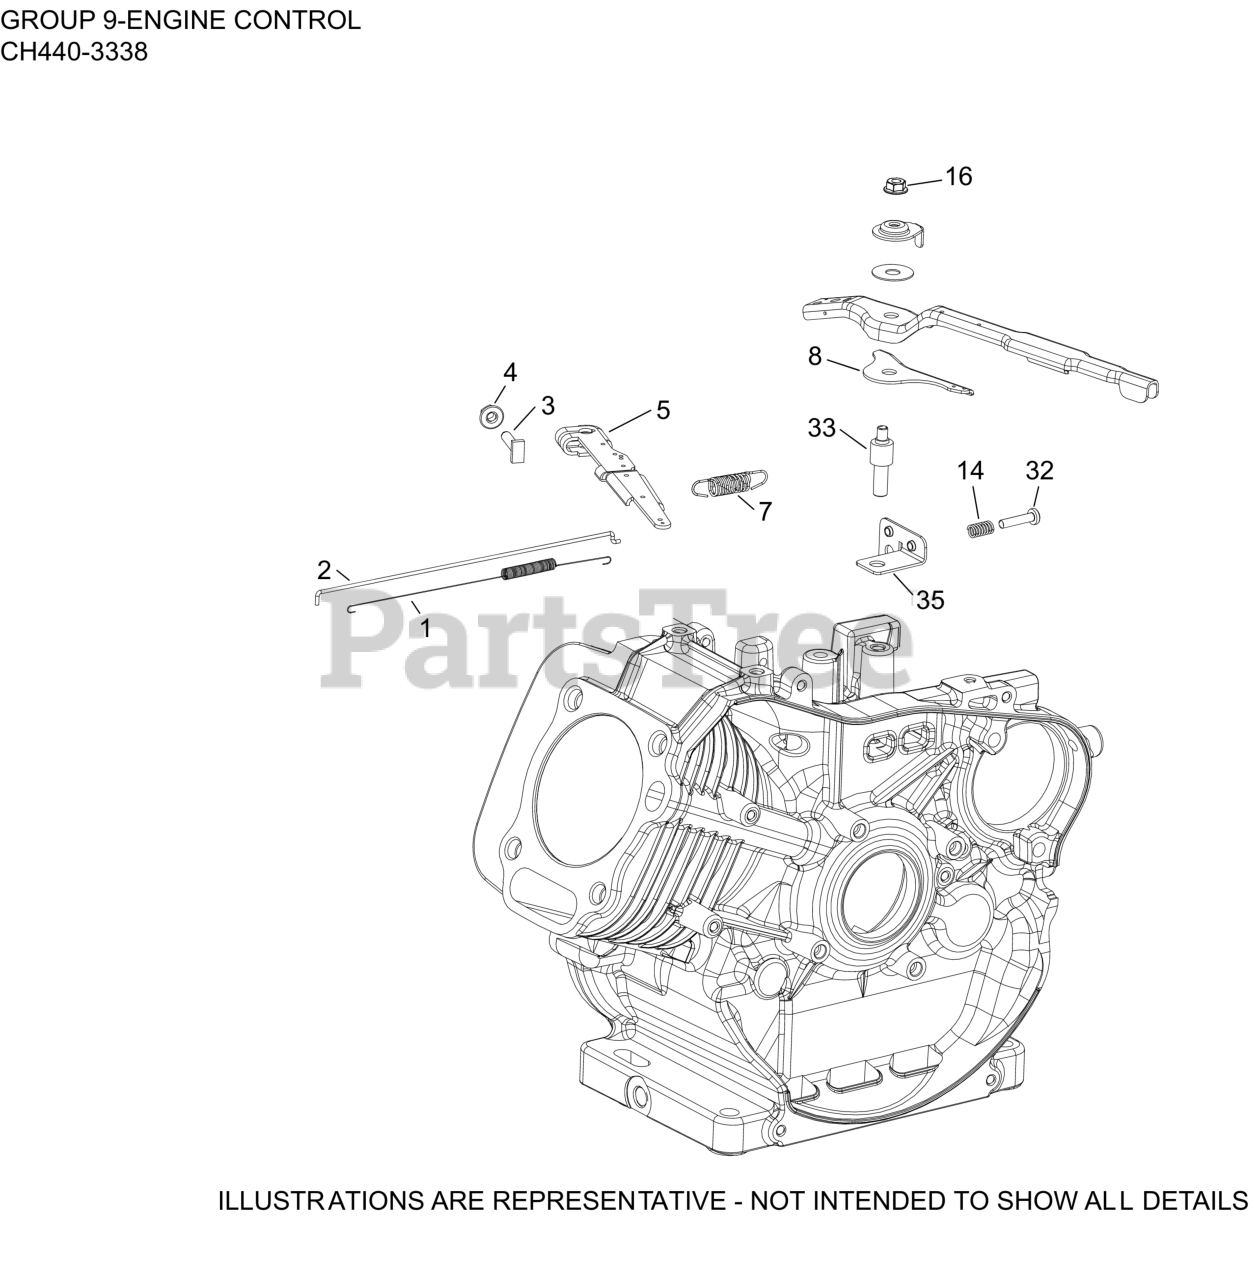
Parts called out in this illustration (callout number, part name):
1	SPRING, LINKAGE
2	LINKAGE, GOVERNOR
3	SCREW, RECTANGLE HEAD (M6)
4	NUT, HEX FLANGE (M6) - USE 14 100 16-S
5	KIT, GOVERNOR LEVER
7	SPRING, GOVERNOR
8	LEVER, FIXED SPEED
14	SPRING, COMPRESSION
16	NUT, HEX FLANGE LOCK (M6)
32	SCREW, SPEED ADJUSTING
33	STUD, CONTROL LEVER
35	BRACKET, CONTROL
